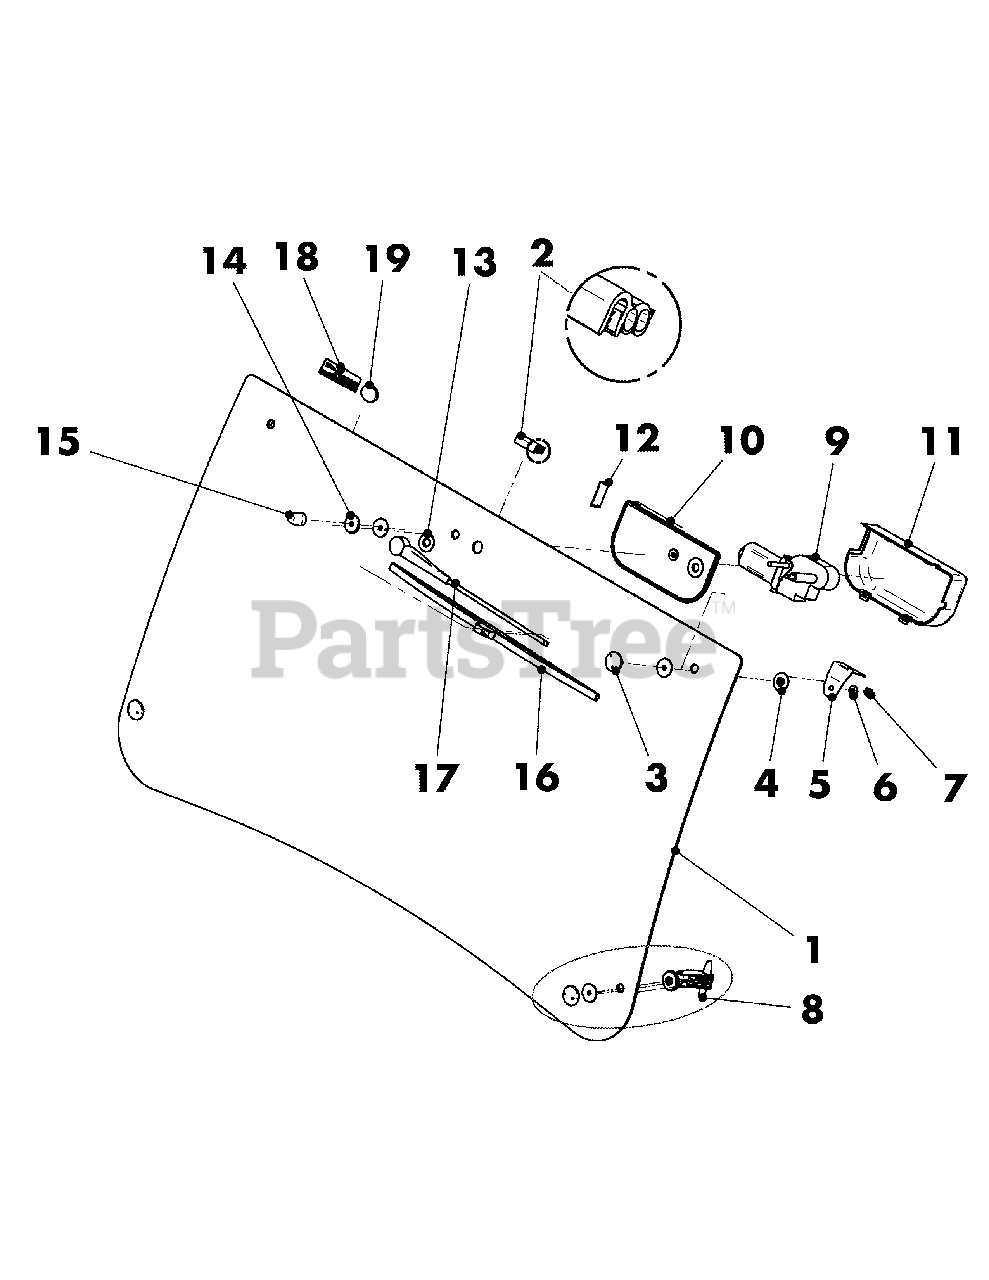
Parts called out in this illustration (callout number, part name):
1	Windshield - Front
9	Wiper Motor, 12 volt
18	Emblem - Winshield
